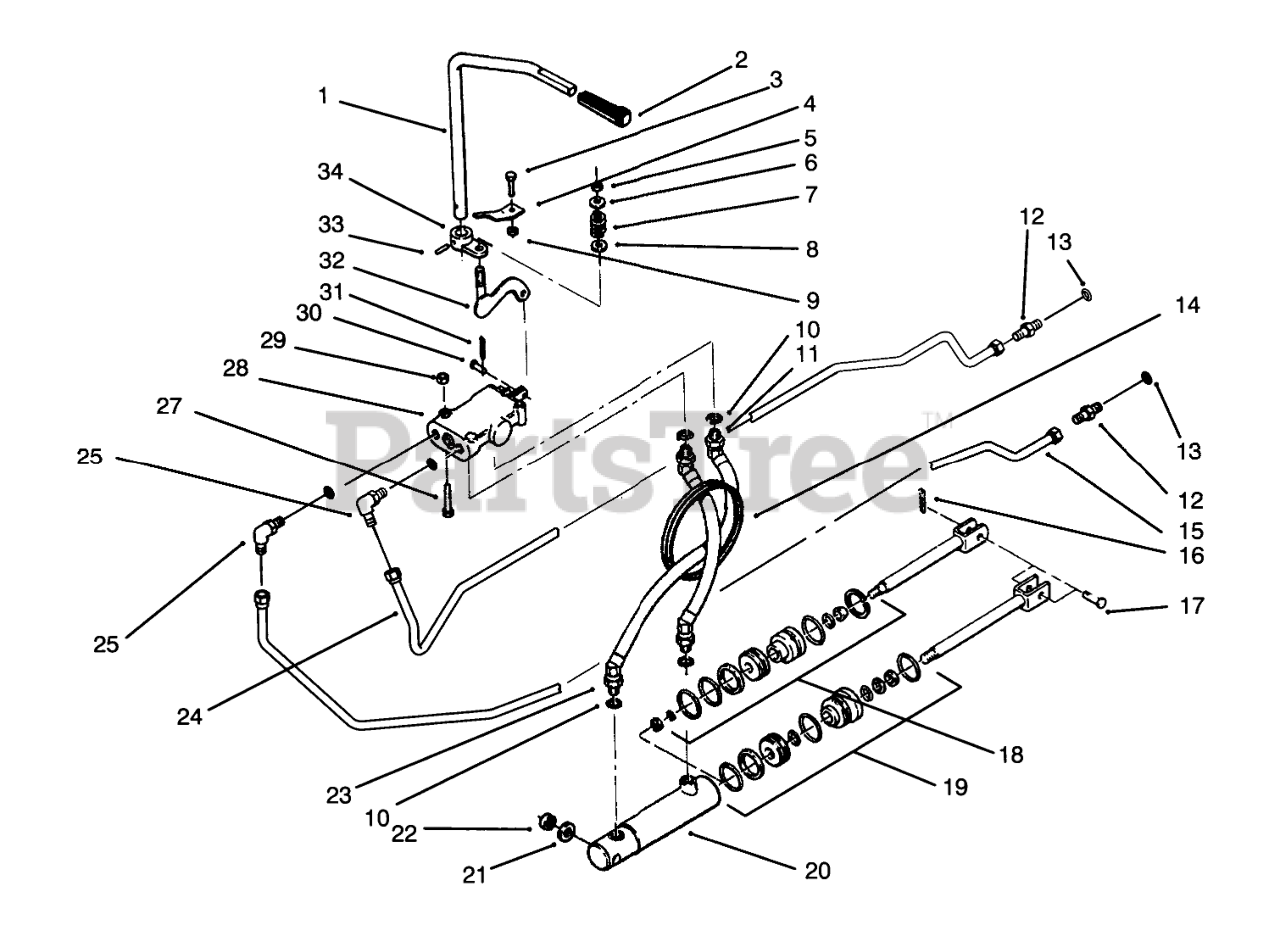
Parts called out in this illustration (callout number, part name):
1	ROD-LIFT CONTROL
2	KNOB-HYDRAULIC LIFT
3	SCREW-HH
4	BRACKET-CONTROL R B
5	NUT-LOCK, NI
7	SPRING
8	SCREW-HH
9	NUT-LOCK, NI
10	O RING
11	Hose ASM-Hydraulic
12	Fitting-Straight Adapter (Incl. Ref. #13)
13	0-Ring
14	GROMMET
15	TUBE-HYD PRESSURE
16	PIN-COTTER
17	CLEVIS PIN
18	S/A O-RING&GASKET AS
19	S/A 108872 HYD CYL
20	Cylinder Hydraulic (Incl. Ref. #18-19)
21	SPACER-WORM SHAFT
22	WASHER
23	Hose ASM-Hydraulic
24	TUBE-HYD RETURN
25	Fitting-90 (Incl. Ref. #13)
27	SCREW-HH
28	Valve-Hydraulic (Incl.Ref. #30-31)
29	NUT-LOCK, NI
30	Pin
31	Cotter Pin
32	WLDMT-LIFT BAR
33	SPIROL PIN 7/32X7/8
34	ARM-CONTROL
